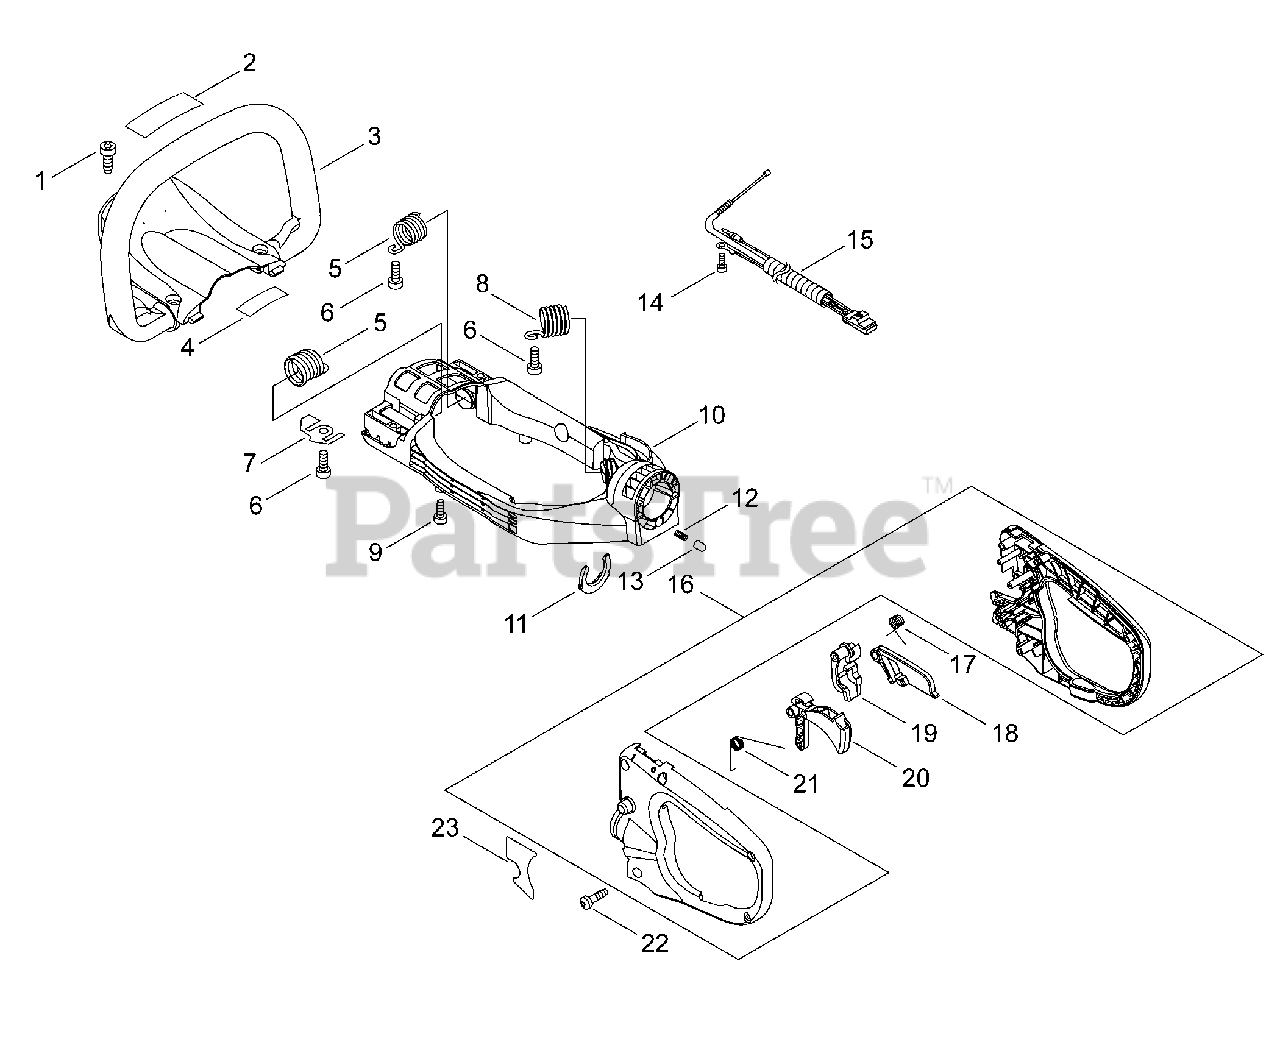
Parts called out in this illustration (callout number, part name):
1	BOLT, TORX 5×20
2	LABEL, CAUTION - ISO
3	HANDLE, FRONT
4	LABEL, CAUTION
5	SPRING, COMPRESSION
6	BOLT, TORX 5×16
7	PLATE, EYE
8	SPRING, COMPRESSION
9	BOLT, TORX 5×12
11	FIXTURE, HANDLE
12	SPRING, COMPRESSION
13	PIN, CLEVIS
14	BOLT, TORX 4×10
15	CABLE ASSY, CONTROL
16	HANDLE SET, REAR
17	SPRING, TORSION
18	LOCKOUT, THROTTLE
19	LEVER, HANDLE RELEASE
20	TRIGGER, THROTTLE
21	SPRING, TORSION
22	BOLT, TORX 4×16
23	LABEL - OPERATION
